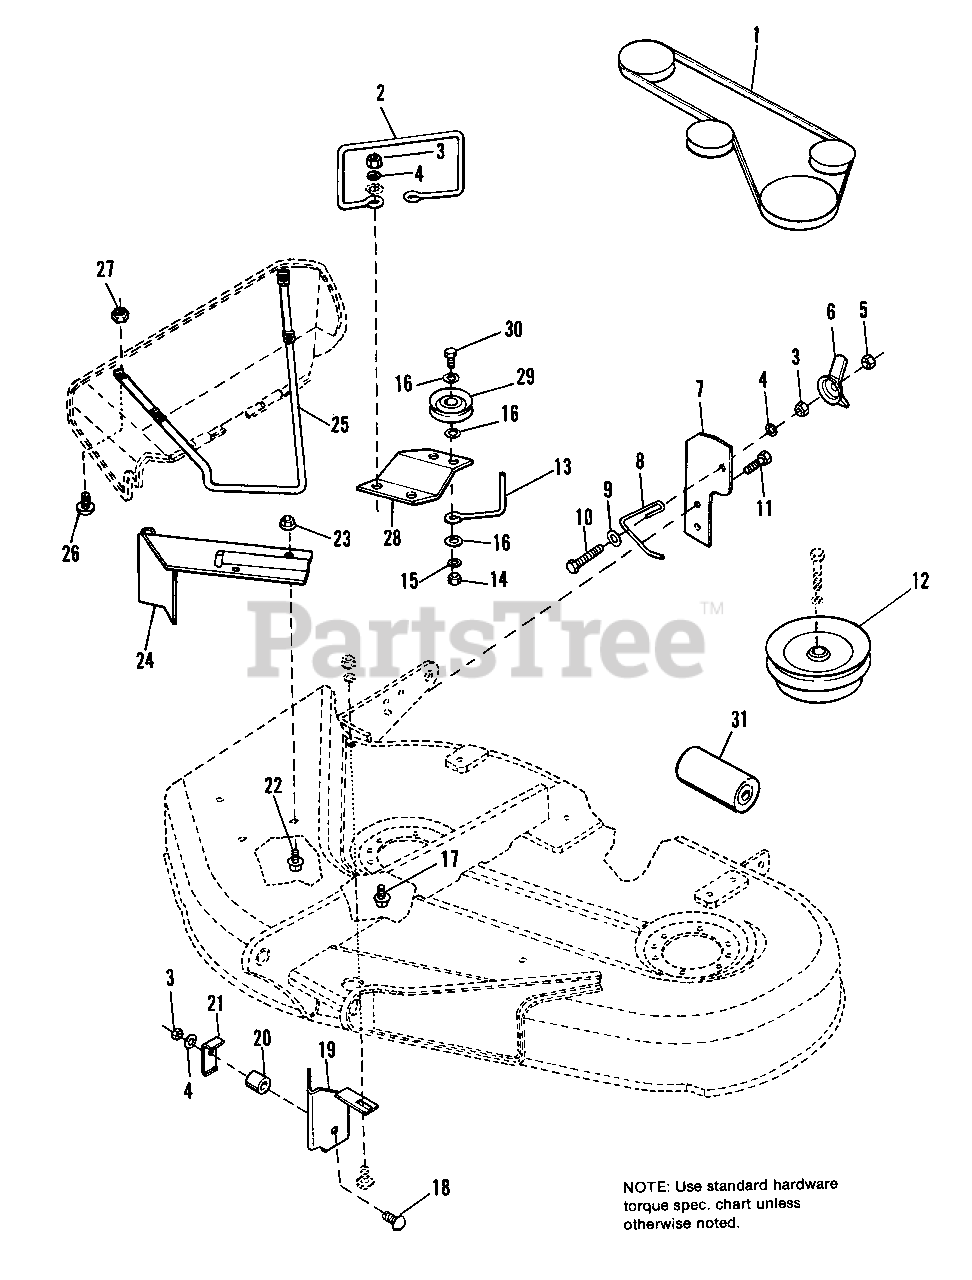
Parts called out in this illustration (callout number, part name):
2	BELT GUIDE, Turbo
3	NUT, Hex, 5/16-18
4	LOCKWASHER, 5/16
5	NUT, Hex, Center Lock, 5/16-18
6	NUT, Wing Assy, 5/16
7	BRACE, 38"
8	SPRING LATCH
9	WASHER, Flat
10	CAPSCREW, Hex Hd, 5/16-18 x 2-1/2
11	SCREW, Taptite, 5/16-18 x 1/2
12	PULLEY ASSY., Turbo
14	NUT, Hex, 3/8-16
15	LOCKWASHER, 3/8
16	WASHER, Flat, 3/8
17	SCREW, Taptite, 5/16-18 x 1-1/2
18	CARRIAGE BOLT, 5/16-18 x 1-1/4
19	BRACKET ASSY., Cut-off
21	BRACKET, "L"
22	CARRIAGE BOLT, 5/16-18 x 3/4
23	NUT, Hex, Flange, Whizlock, 5/16-18
24	PIVOT ASSY., 38"
25	ROD, Deflector
26	SCREW, Truss Hd., #10-24 x 3/4
27	NUT, Nylock, #10-24
28	BRACKET, Idler, Turbo
29	PULLEY ASSY., Idler
30	CAPSCREW, 3/8-16 x 1-1/4
